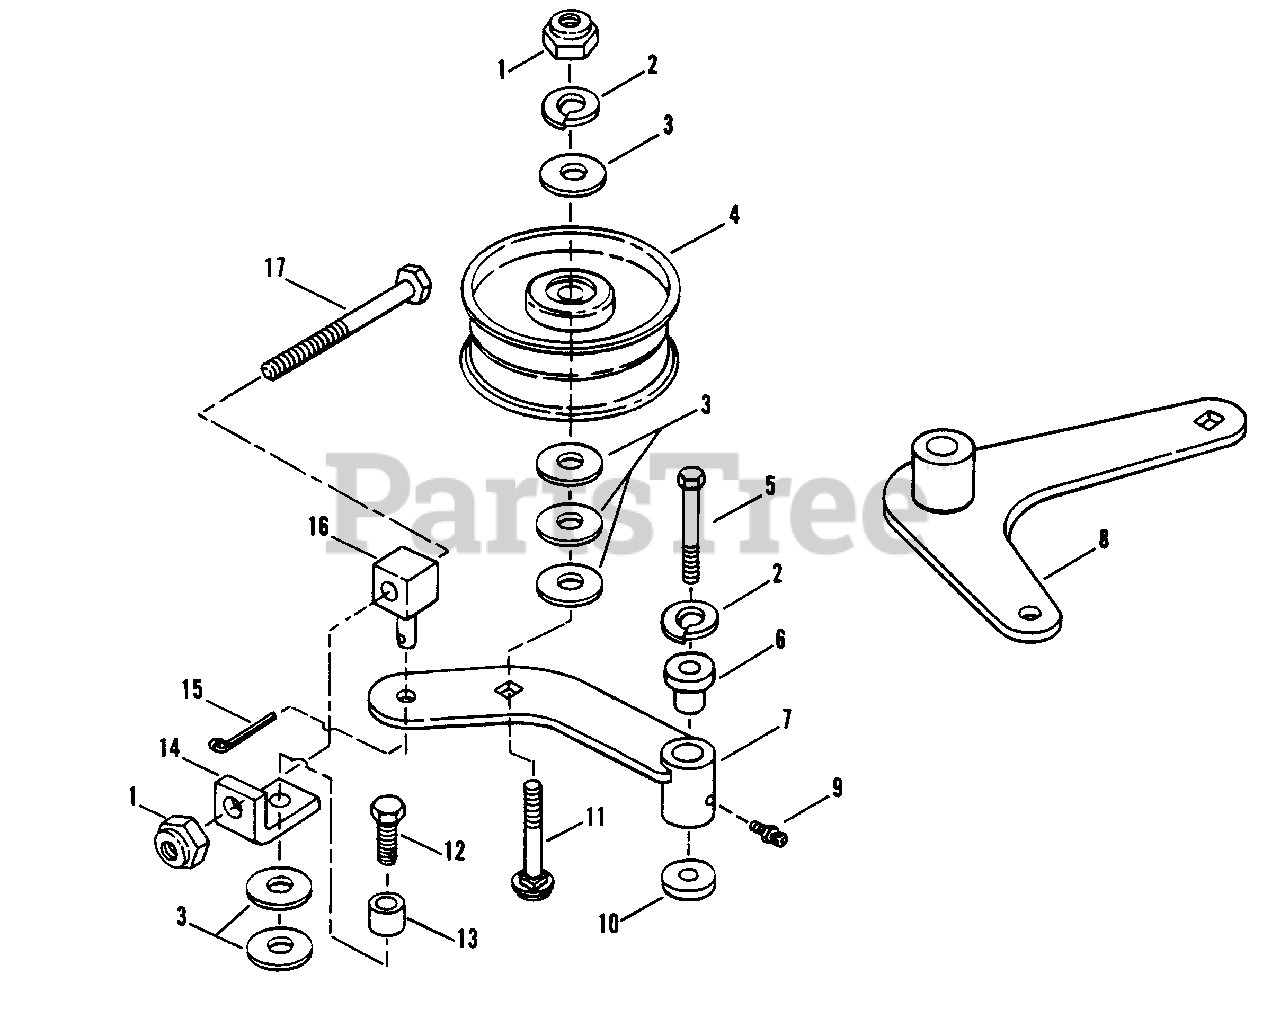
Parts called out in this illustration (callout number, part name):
1	NUT, 3/8-16 Nyloc
2	WASHER, 3/8 Lock
3	WASHER, Flat
4	PULLEY, Idler
5	BOLT, 3/8-16 x 3" Hex Head
6	PIVOT, Spacer
7	IDLER ARM WELDMENT (36")
8	IDLER ARM WELDMENT (48")
9	ZERK, 1/4-28
10	BUSHING
11	BOLT, 3/8-16 x 2 1/2" Carriage
12	BOLT, 3/8-16 x 1"
13	SPACER, Blade Engagement
14	ANGLE, Blade Engagement
15	COTTER-PIN, 3/32 x 1"
16	SWIVEL
17	BOLT, 3/8-16 x 5" (Tap)
